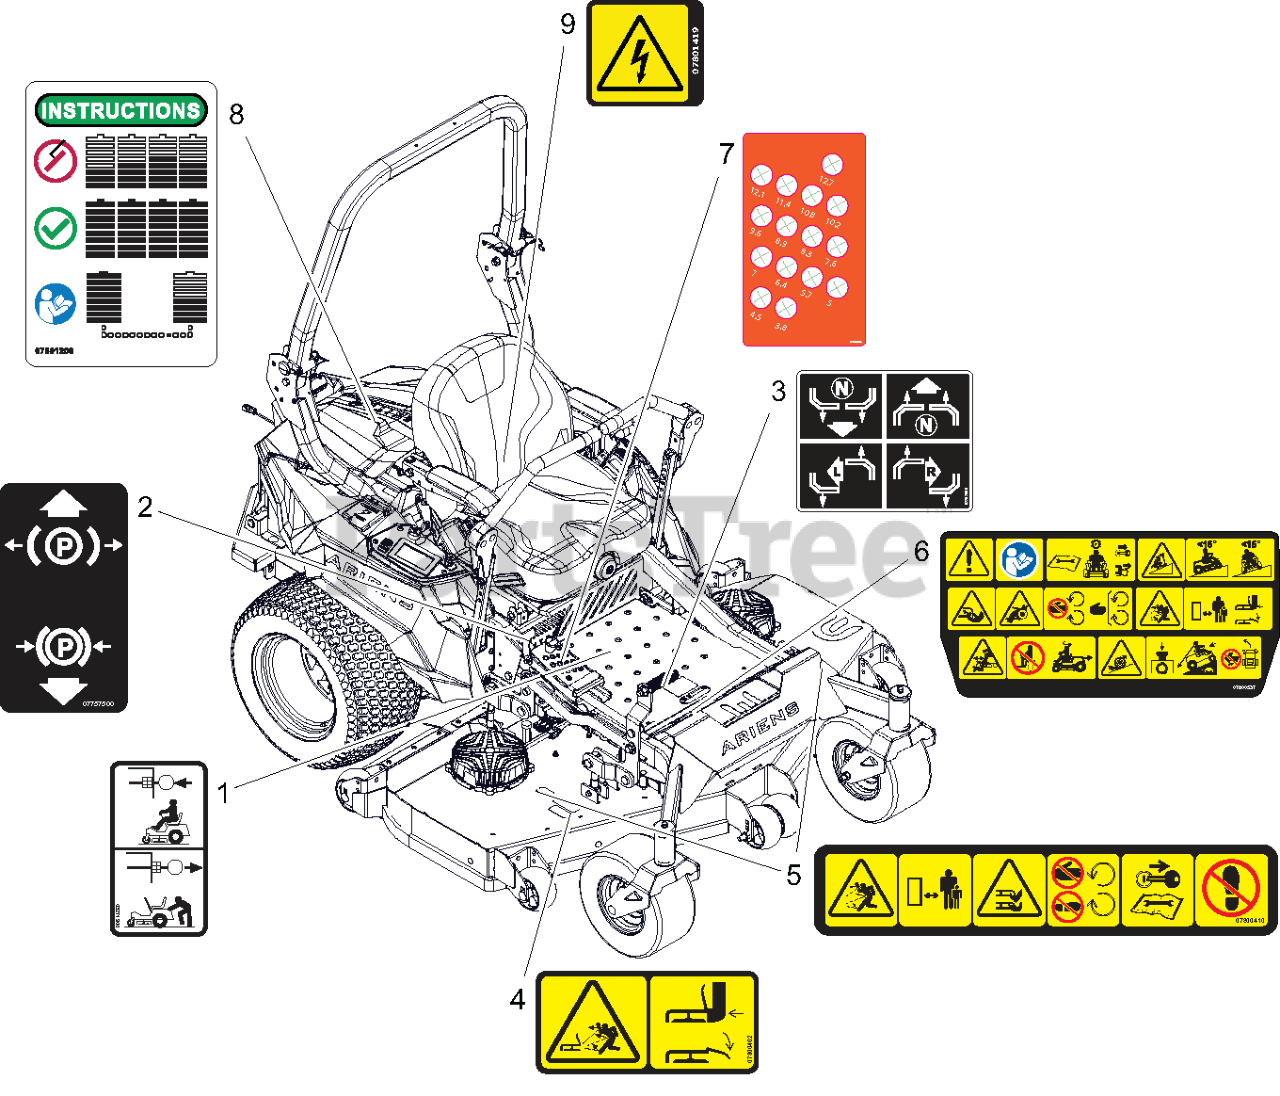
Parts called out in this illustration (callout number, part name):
1	DECAL, TRANSMISSION DISCONNECT
2	DECAL, PARKING BRAKE LEVER
3	DECAL, INSTRUCTIONAL-STEERING
4	DECAL, SAFETY - DECK GUARDING
5	DECAL, DECK SAFETY
6	DECAL, MAIN SAFETY
7	DECAL, APEX HOC METRIC
8	DECAL, BATTERY BALANCE
9	DECAL, SAFETY - DANGER
